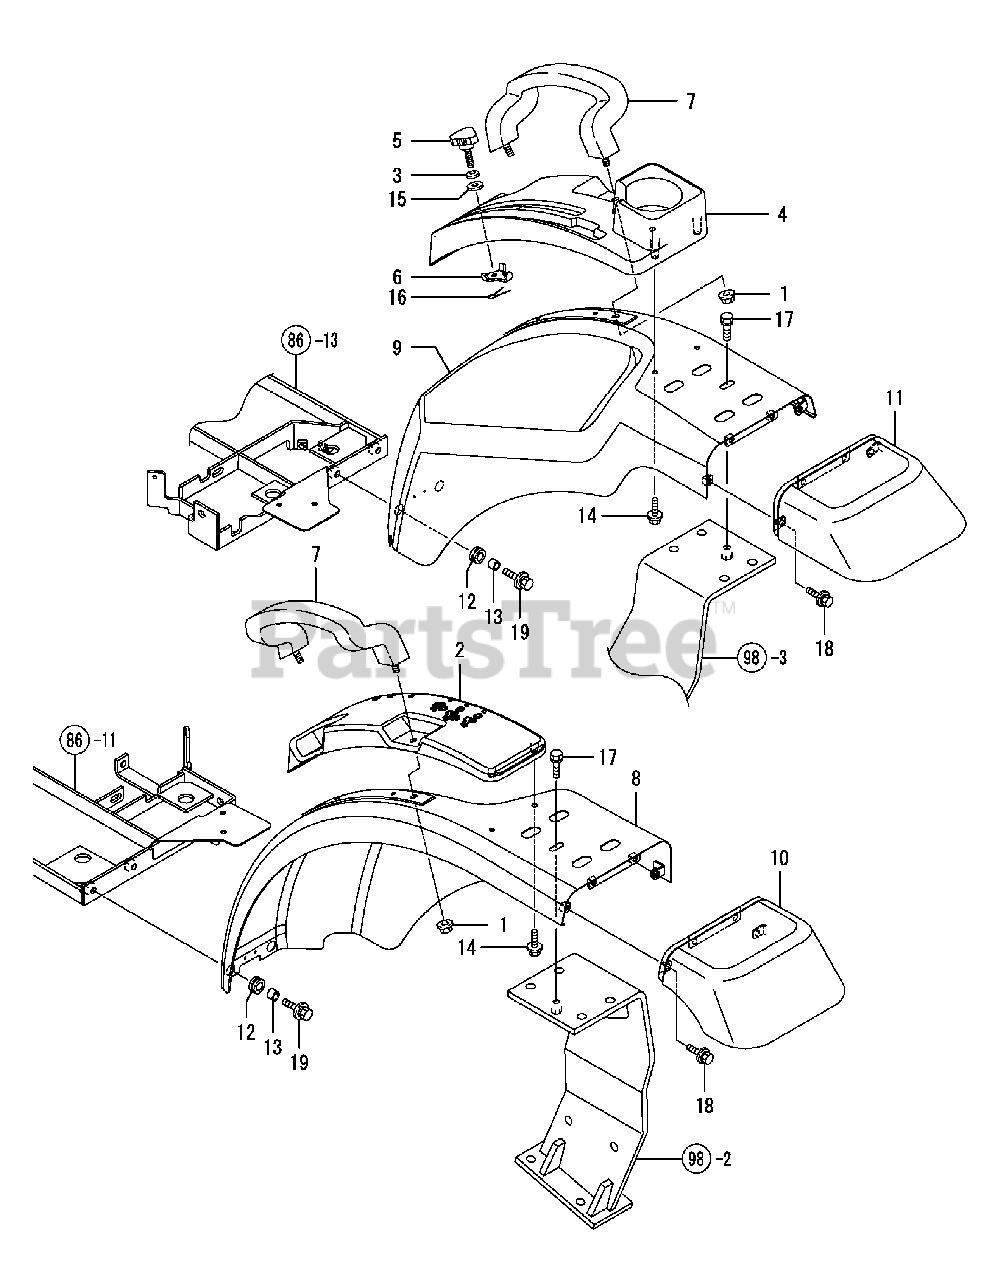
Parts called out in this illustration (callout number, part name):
1	Nut W/Washer 8
2	Guide, Change Lever
3	Spring, Conical
4	Guide, Hyd.Lever
5	Knob, Hyd.Control
6	Stopper, Hyd.Control
10	Fender Ext L Cmp
11	Fender Ext R Cmp
13	Collar 8.8X12X10
14	Screw, Fender Cover
16	Cotter Pin 2.0X16
